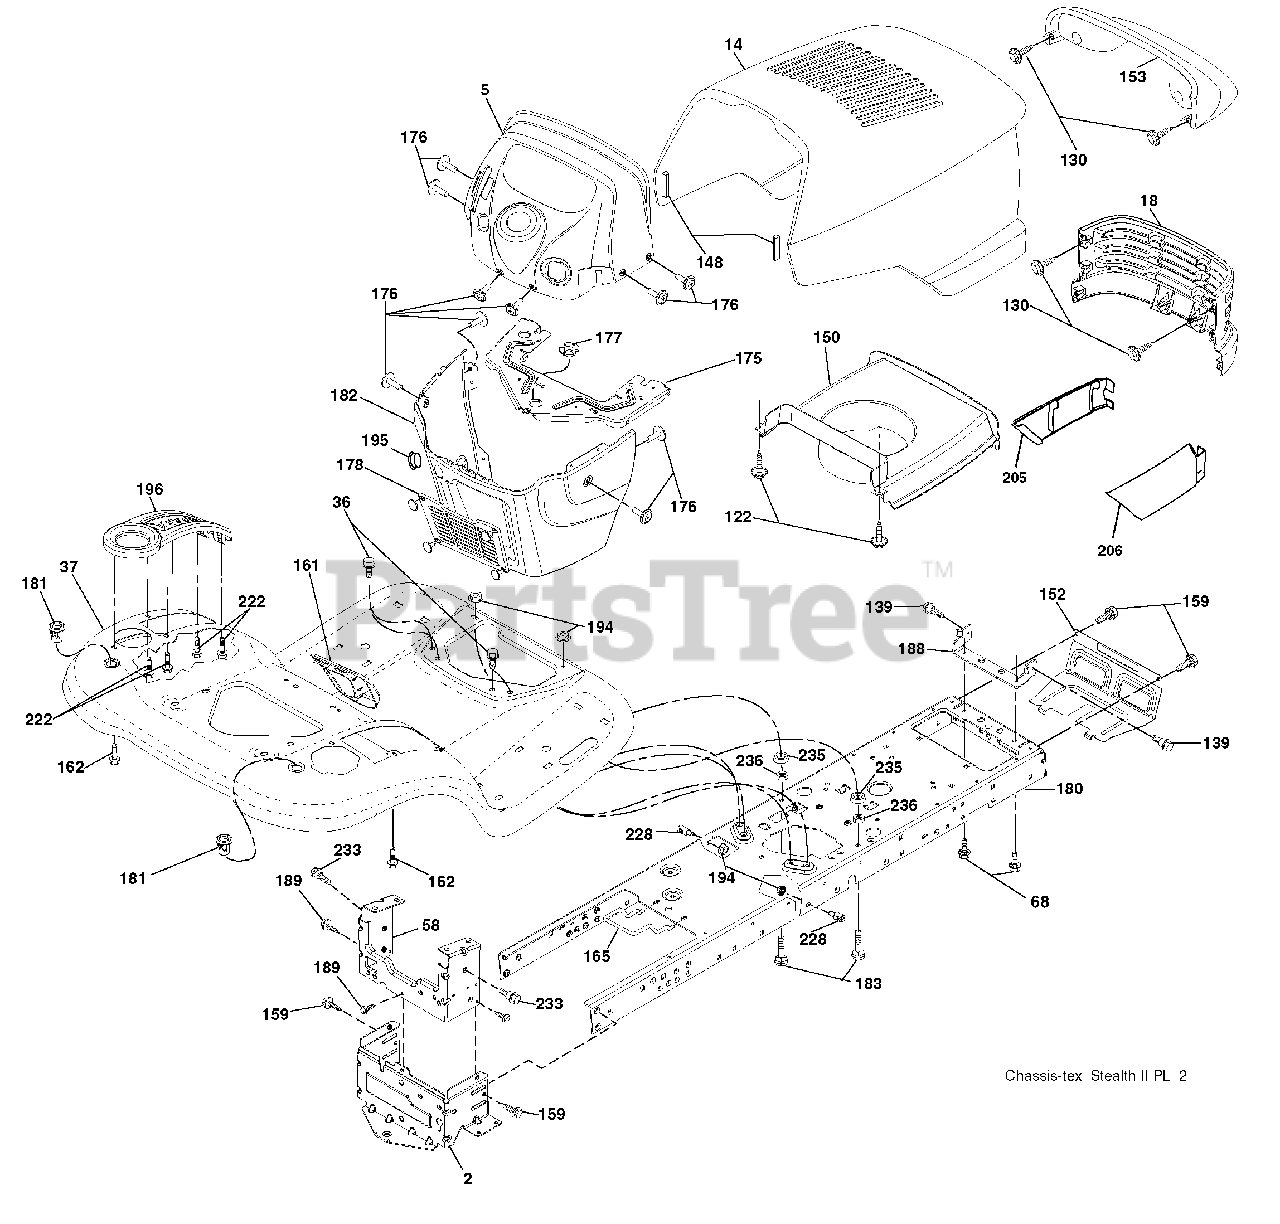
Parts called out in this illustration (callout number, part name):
2	Drawbar Lower
5	Dash
14	Hood
18	Grille
36	Screw 5/16-18 x 3/4
37	Fender
58	Drawbar Upper
68	Screw 5/16-18 x 1/2
122	Screw WSHD Hex 10-32 x 5/8
130	Screw #10 x 0.750 BOS Thread
139	Bolt Shoulder 5/16 - 18
148	Bumper Hood
150	Duct Heat
152	Shield Browning/Debris
153	Lens Bar
159	Screw Hex Wsh. Thdrol. 3/8-16 x 3/4
161	Window Fuel
162	Screw Hex Wsh Hi-Lo 1/4 x 1/2 unc
165	Bracket Support Tank
175	Cross Member
176	Screw 10-24 x 5/8 Wshd. Qdrx.
177	Bushing Steering
178	Cargo Asm. Net
181	Bushing Mtg. Fender Crgo.
182	Dash Lower
183	Bolt Fin. Hex 5/16-18 x 1-1/4
188	Bracket Pickoff Hood
189	Screw 5/16-18 x 3/4
194	Nut Lock Hex Flange 5/16-18
195	Plug Hole Dash
196	Console Asm. Deck Lift
205	Skirt Hood RH
206	Skirt Hood LH
222	Screw Thrdrol. 1/4-20 x 5/8
228	Stud Fastener
233	Bolt Shoulder
235	Spacer Fender
236	Nut Lock 5/16-18
